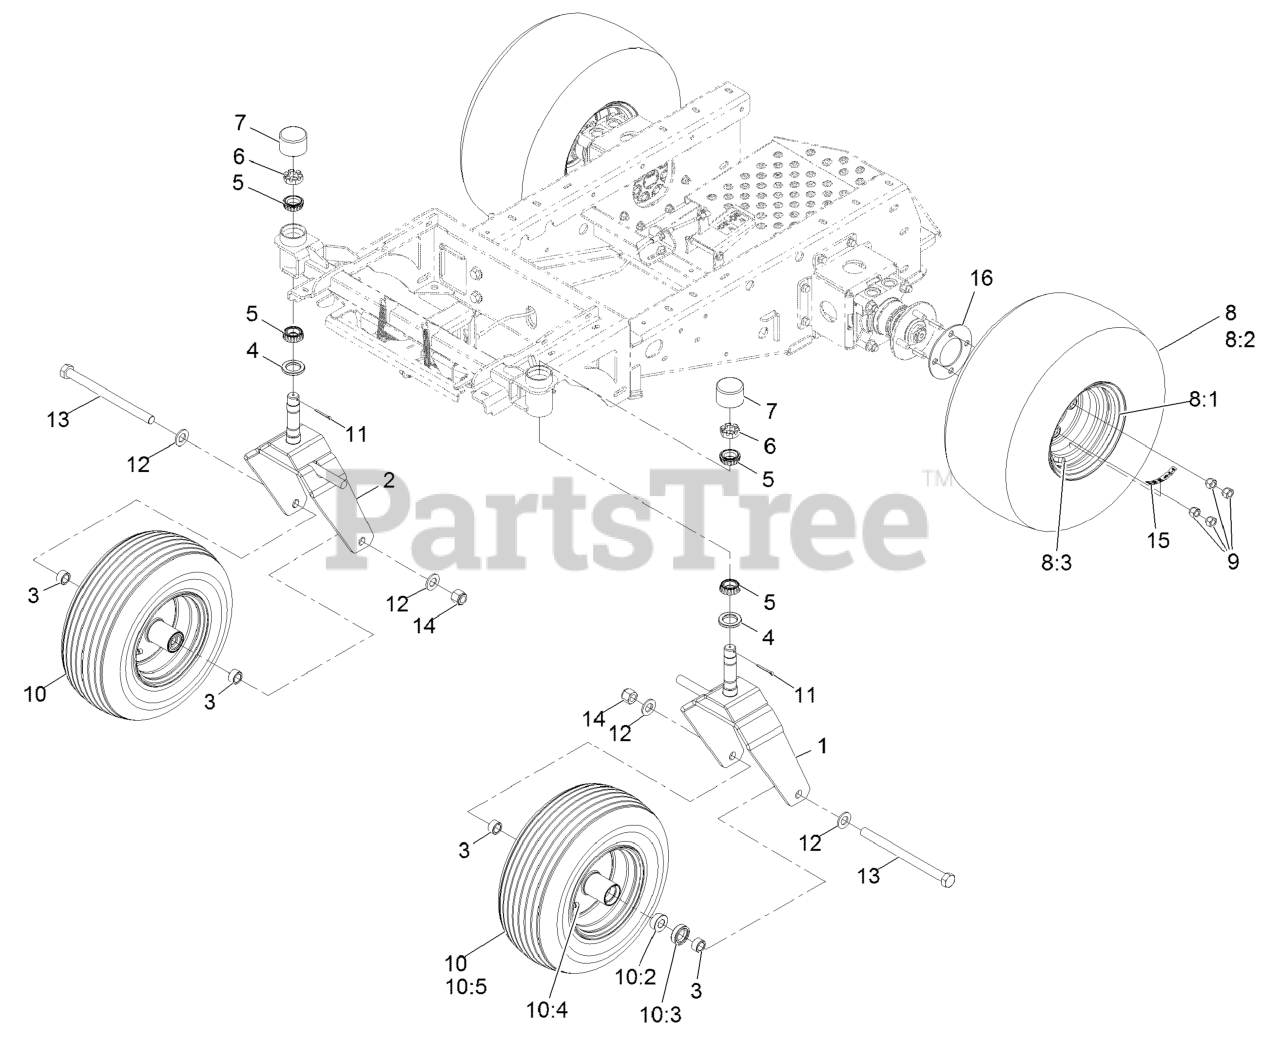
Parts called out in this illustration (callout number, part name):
1	X-REF TO 135-5441-03
2	X-REF TO 135-5446-03
3	SPACER-AXLE
4	SEAL-GREASE
5	CONE-BEARING, OUTER
6	NUT-SHH
7	CAP-DUST, RUBBER
8	WHEEL AND TIRE ASM
8:1	Rim-8 X 7, Black
8:3	Stem-Valve
9	NUT-LUG
10	WHEEL AND TIRE
10:2	BEARING-CONE, TAPERED ROLLER
10:3	SEAL-CASTER
10:4	VALVE
10:5	Tire-Rib
11	Pin-Cotter
12	WASHER-FLAT
13	SCREW-HH
14	NUT-LOCK, NI
15	DECAL-TORQUE, WHEEL HUB LUG
16	SPACER-WHEEL
